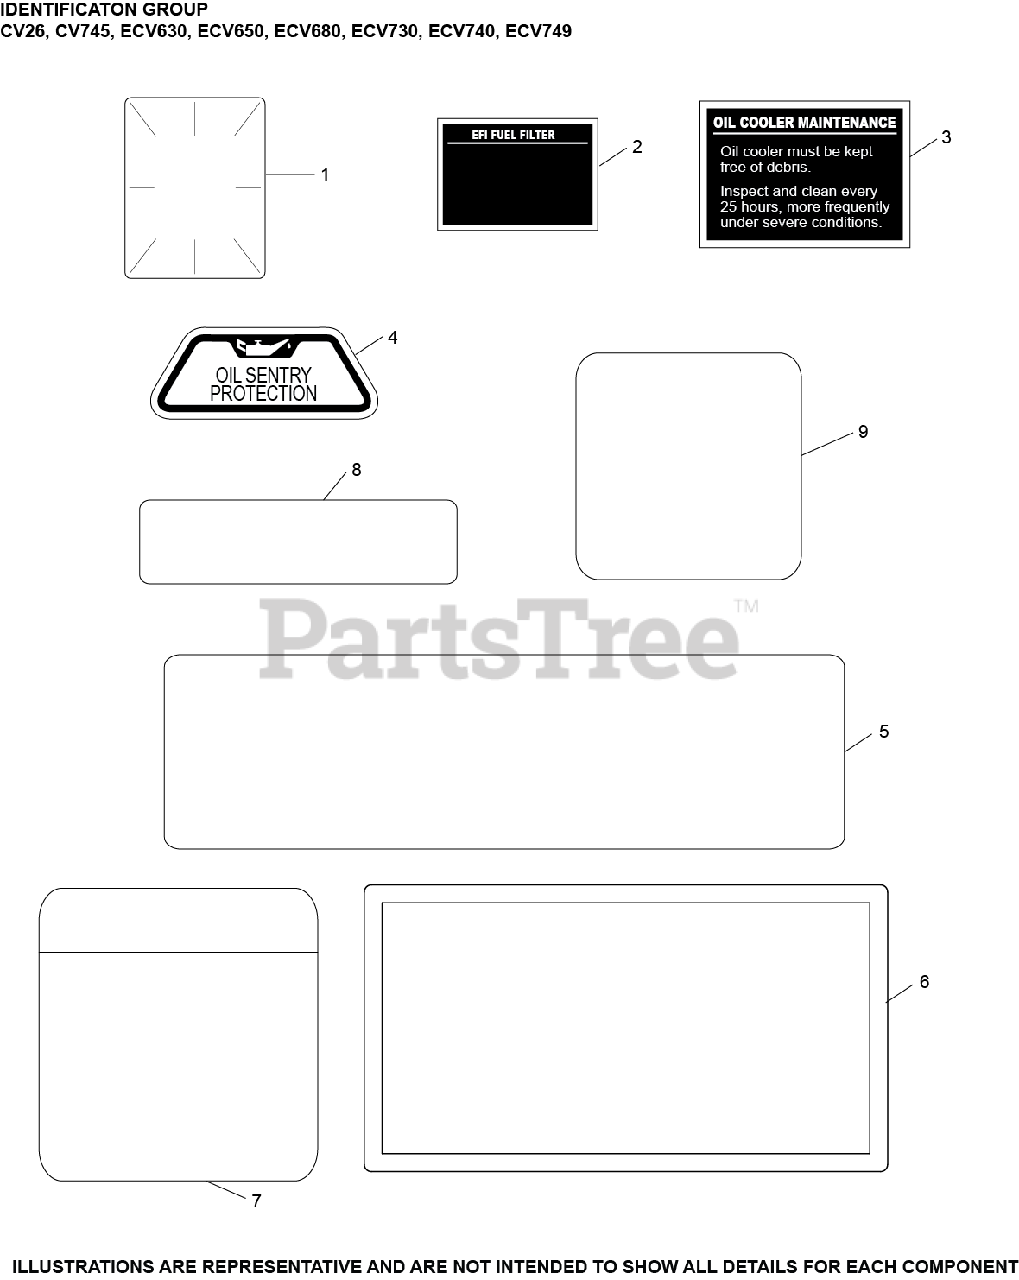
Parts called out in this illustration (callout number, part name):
1	LABEL, CLEAR LAMINATION - USE 25 113 79-S
2	LABEL, EFI FUEL FILTER
9	DECAL HDAC, ECV650/694cc
